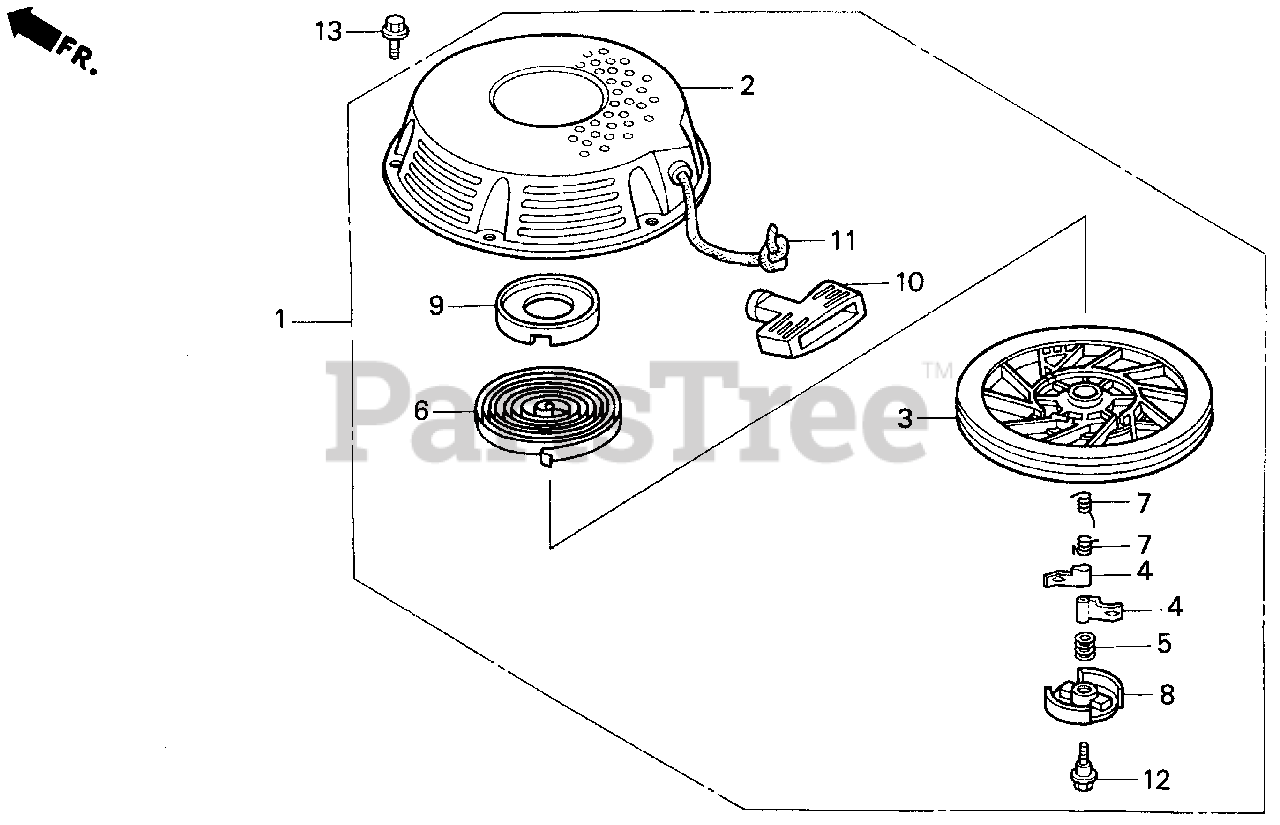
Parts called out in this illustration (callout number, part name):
1	STARTER ASSY., RECOIL *R8* (Honda Code 4186318). (BRIGHT RED)
1	STARTER ASSY., RECOIL *R280* (Honda Code 7660962). (POWER RED)
2	CASE, RECOIL STARTER *R8* (Honda Code 4186326). (BRIGHT RED)
3	PULLEY, RECOIL STARTER
4	RATCHET, STARTER
5	SPRING, FRICTION
6	SPRING, STARTER RETURN
7	SPRING, RATCHET
8	RETAINER, SPRING
9	HOLDER, SPRING
10	GRIP, STARTER
11	ROPE, RECOIL STARTER (#6X54")
12	SCREW, CENTER
13	BOLT, FLANGE (6X10)
